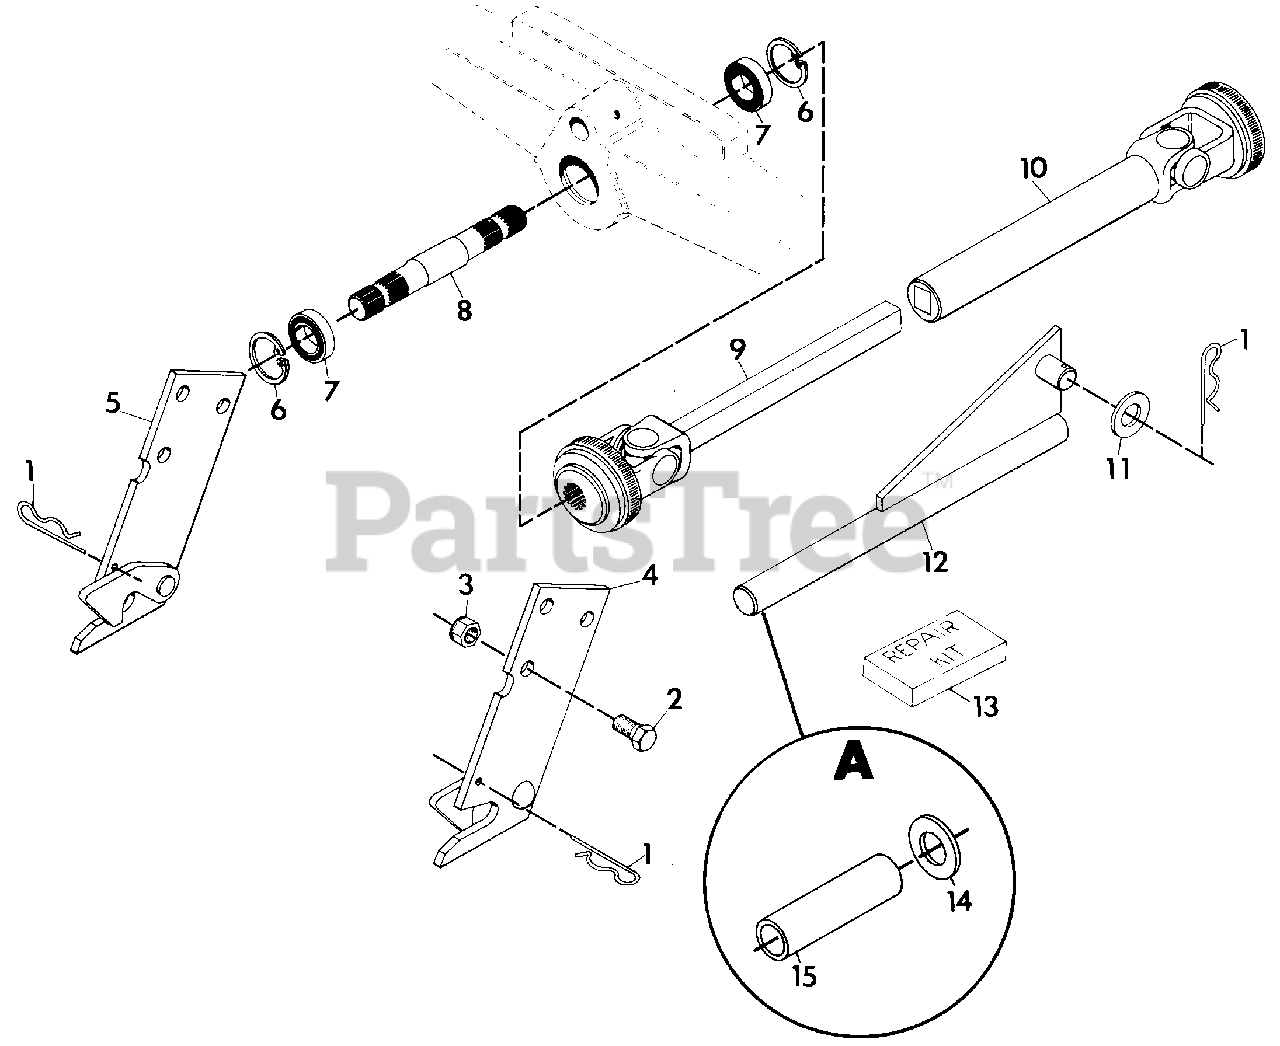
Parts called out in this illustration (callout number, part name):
1	PIN, HAIR
2	BOLT, HEX 1/2-13X1
3	NUT, HEX 1/2-13
4	ASSEMBLY, ATTACHMENT BRACKET L.H.
5	ASSEMBLY, ATTACHMENT BRACKET R.H.
6	RING, RETAINING 2.062 BORE
7	BEARING, BALL .984X2.047X.590
8	SHAFT, FRT PTO
9	JOINT, U, MALE END
10	SHAFT, FRT PTO PROP.
11	WASHER, FLAT .812X1.496X.134
12	GUIDE, PUSH ROD WELDMENT
13	KIT, REPAIR U-JOINT(NEAPCO)
14	WASHER, FLAT 1.062X2.000X.134
15	SPACER
